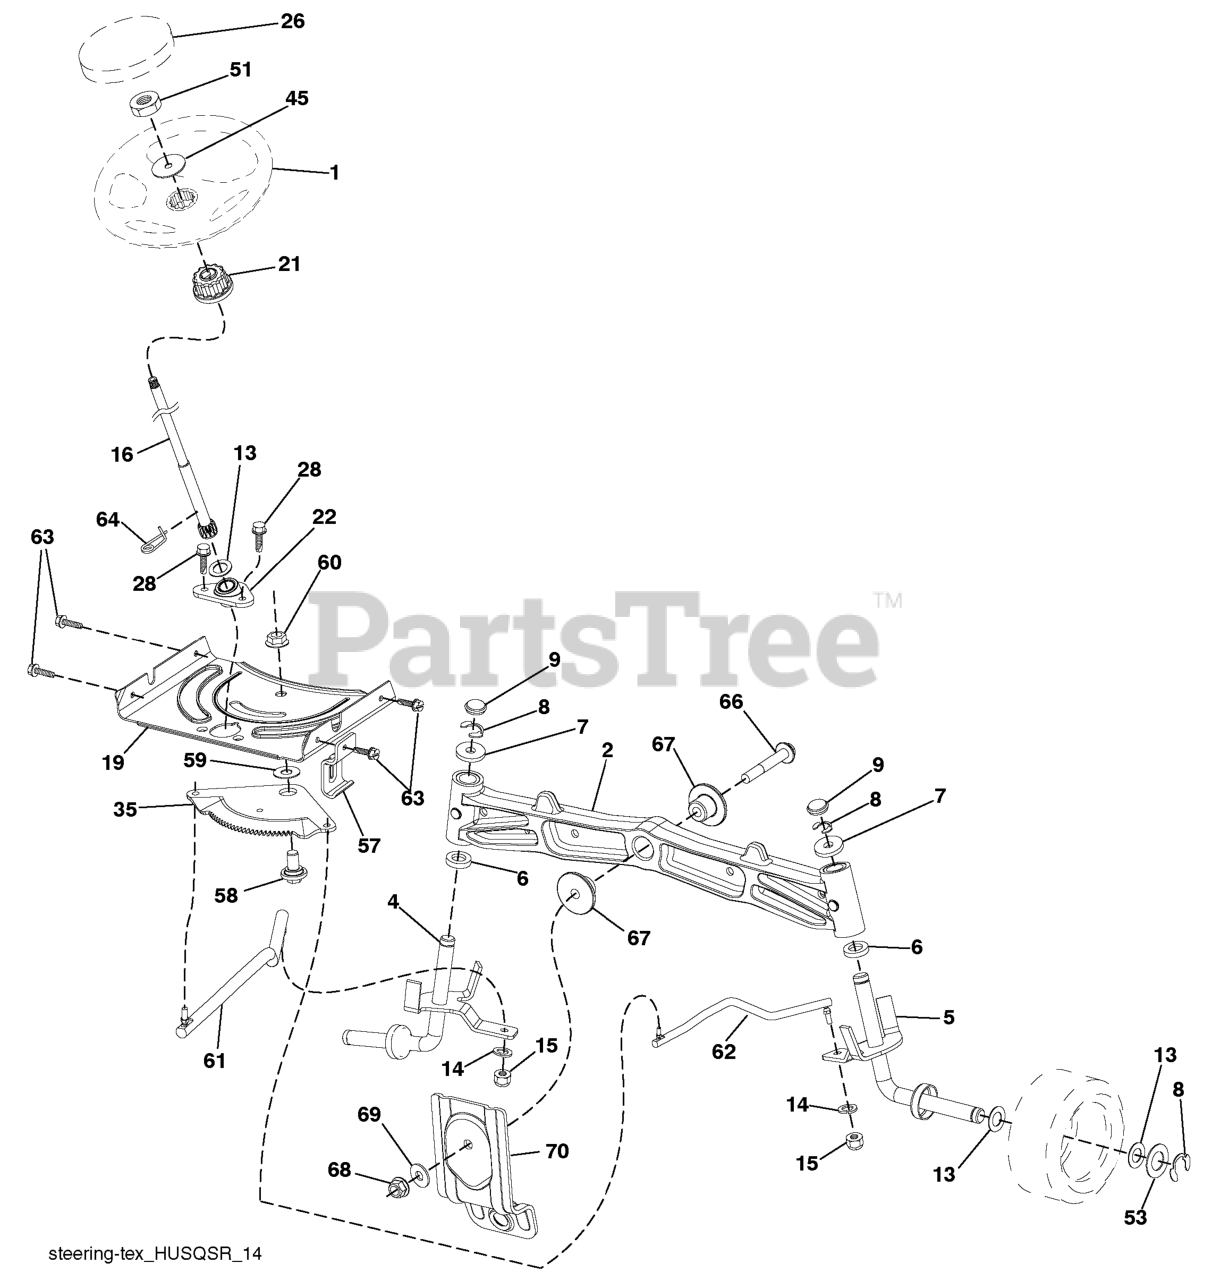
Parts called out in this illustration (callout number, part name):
1	RP WHEEL.STEER.HUSQ.PREM.OVMLD
2	AXLE.CAST.IRON
4	SPINDLE.WELDED.LH.16"TEX
5	SPINDLE.WELDED.RH.16"TEX
6	THRUST WASHER
9	CAP.SPINDLE.BLACK
14	WASHER, LOCK 3/8
15	NUT CROWNLOCK 3/8-24
16	SHAFT, STEERING
19	PLATE.STEER.DDL.NLT/NG
21	ADAPTER, WHEEL STNG..
22	STEERING.SUPT.LOWER.
26	RP INSERT.CAP.WHL.STRG.HUSQ.
28	SCREW, 3/8-16X3/4
35	GEAR.SECTOR.PLATE.DDL.
45	WASHER 9/16"ID, 2 3/8"OD
51	NUT.HEX.1/2-20
53	WASHER.HARDENED
57	BRKT.UPSTOP.GT/LT.TEX
58	BOLT.SHOULDER.SECTOR.P
59	WASHER.THURST.SECTOR.S
60	NUT FLANGE LOCK 5/8-11
61	DRAGLINK.LH.BALLSTUD.D
62	DRAGLINK.RH.BALLSTUD.D
63	SCREW
64	RETAINER.CLIP.SPRING.S
66	BOLT HEX FGHD 7/16-14 X 3 SERR
67	BUSHING.PM.FRONT AXLE
68	NUT.LOCK.FLANGE.7/16
69	WASHER.1.5X.505X.118
70	BRKT.DECK.SUSPENSION.F
